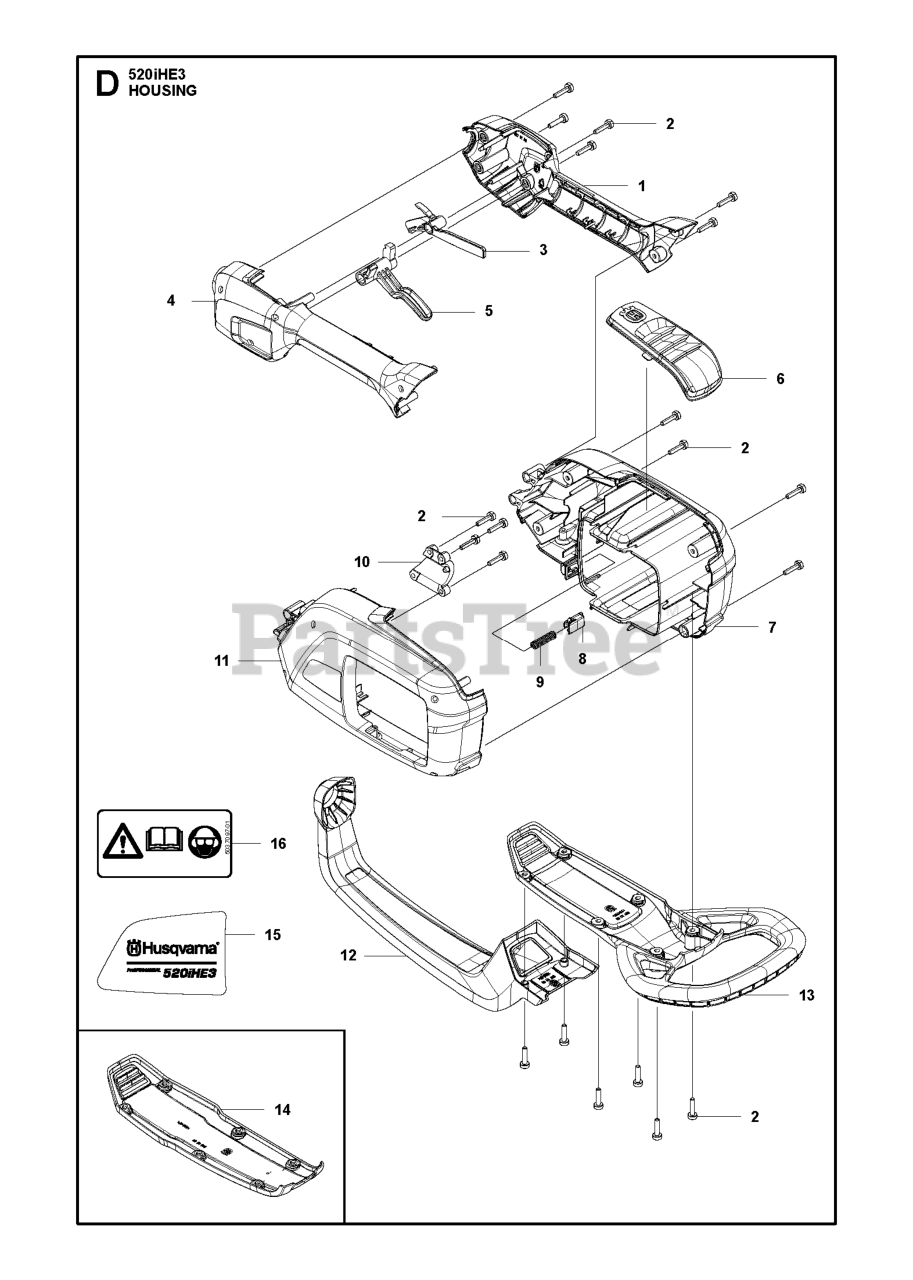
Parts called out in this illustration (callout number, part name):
1	HANDLE HALF RIGHT
2	SCREW
3	THROTTLE LOCKOUT
4	HANDLE HALF LEFT
7	HOUSING RIGHT
8	PUSH BUTTON
9	SPRING PUSH OUT
11	HOUSING LEFT
12	TRIGGER GUARD
13	BUMPER SKID PLATE
14	SKID PLATE
15	DECAL PRODUCT 520IHE3
